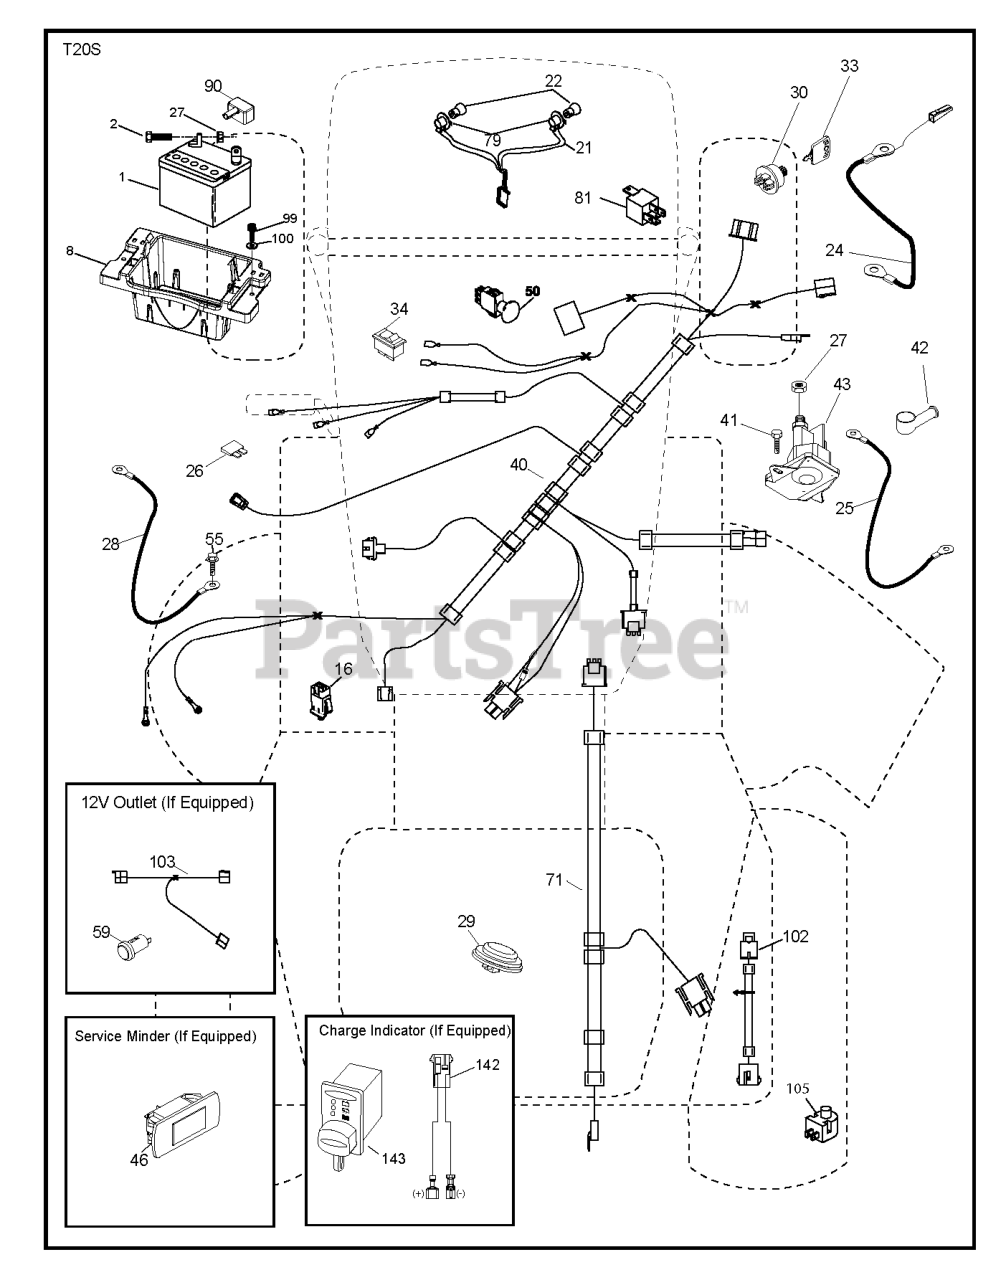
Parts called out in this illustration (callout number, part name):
1	Battery, Dry 30 Amp
2	BOLT.HEX.1/4.X.3/4.DICHROMATE
8	BOX.BATTERY.MOUNT.FRONT.LT
16	SWITCH INTERLOOK PUSH-IN
21	HARNESS.LIGHT W/4152J BULBS
24	CABLE.FRBATT.W/WIRE.8GA.8
25	CABLE.STARTER.8GA.17.5
26	FUSE 20AMP
27	NUT
28	CABLE.GROUND.21"BLK.8GA.90T
29	SWITCH.SEAT.DELTA.OPC.
30	SWITCH.IGN.DELTA.W.LGH.ROS
33	KEY.CHAIN.BLISTER.PACK.GEN.USA
40	HARNESS.IGN.ELEC.RELAY.TEX.46"
41	SCREW
42	TERMINAL COVER
43	SOLENOID.W/BRASS.PLUNGER
46	GUAGE.SRVCMNDR.HRMTR.
50	RP.PTO.SWITCH.8 TERMINAL.BLACK
55	SCREW 5/16"
59	OUTLET.12-VOLT
71	HARNESS-CHASSIS SUB
79	BULB HOLDER ASM.
81	RELAY HARNESS.SEALED
90	COVER.TERMINAL.BATTERY
91	STRAP.BATTERY.MOUNT.FRONT(2 2)
99	SCREW HEXWSHR 1/4-20X3/4
100	WASHER
102	HARNESS PIGTAIL PCH TEX ROS
103	HARNESS PIGTAIL 12V OUTLET
105	REVERSE SWITCH
142	CHARGE.PORT.PIGTAIL HARNESS
143	CHARGE.PORT
